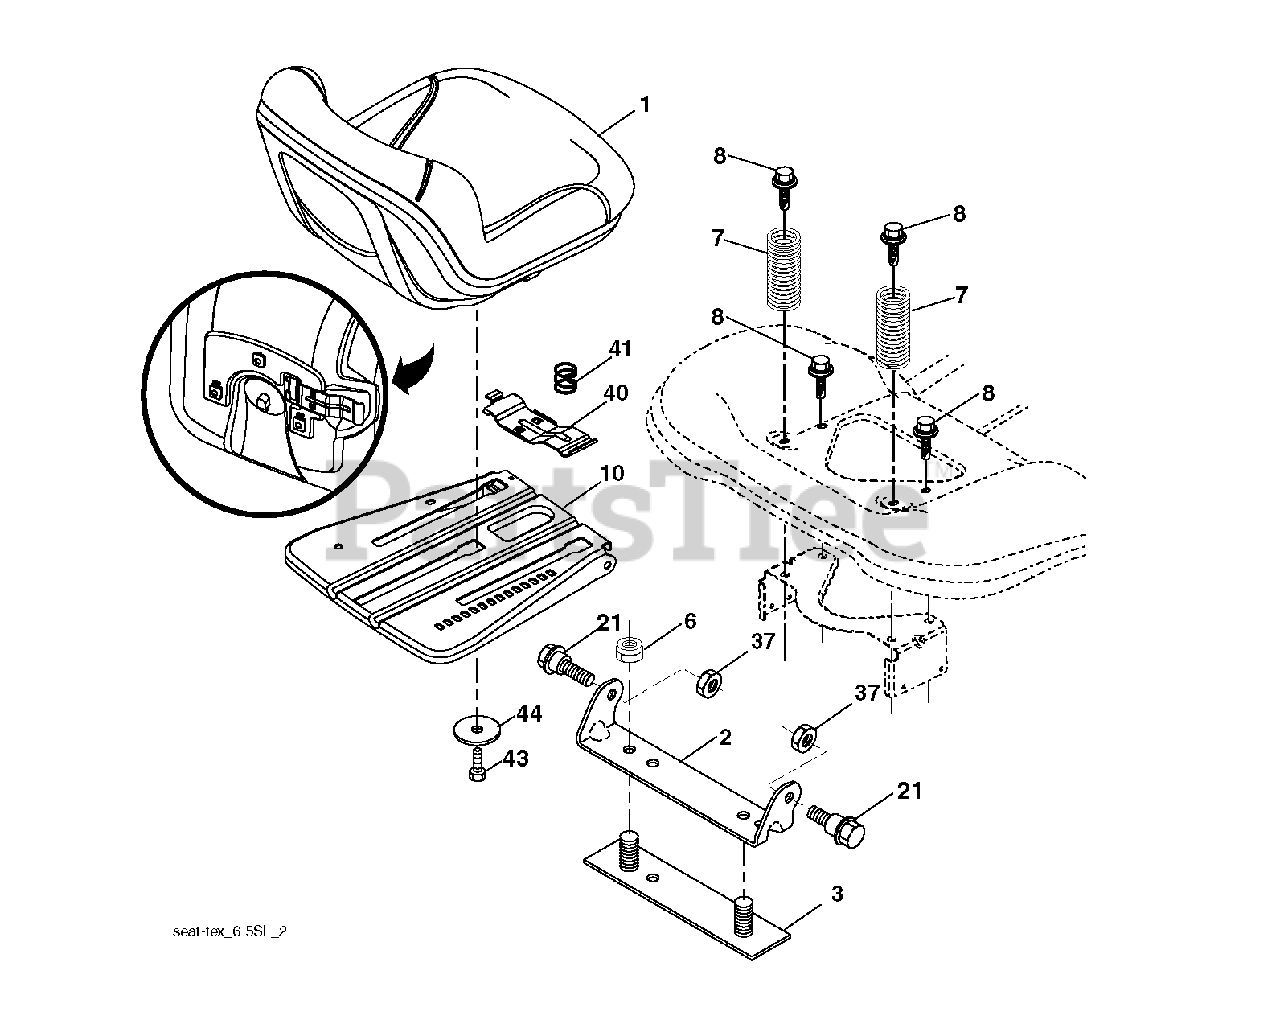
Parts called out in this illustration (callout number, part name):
1	SEAT.TG130.BLACK.NO/LOGO.
2	BRKT.PIVOT.FENDER
6	NUT
7	SPRING COMPRESSION
8	BOLT, 5/16-18 X 1 3/4
10	PAN.ASM.SEAT.3PT
21	BOLT.SHOULDER.5/16-18
37	NUT.71038.31-18.HEX.NYLOCK
40	HANDLE.SLIDE.SEAT.TEX.BLACK
41	SPRING.LATCH.SEAT.TEX
44	WASHER 13/32 X 2-3/8 X 12GA
